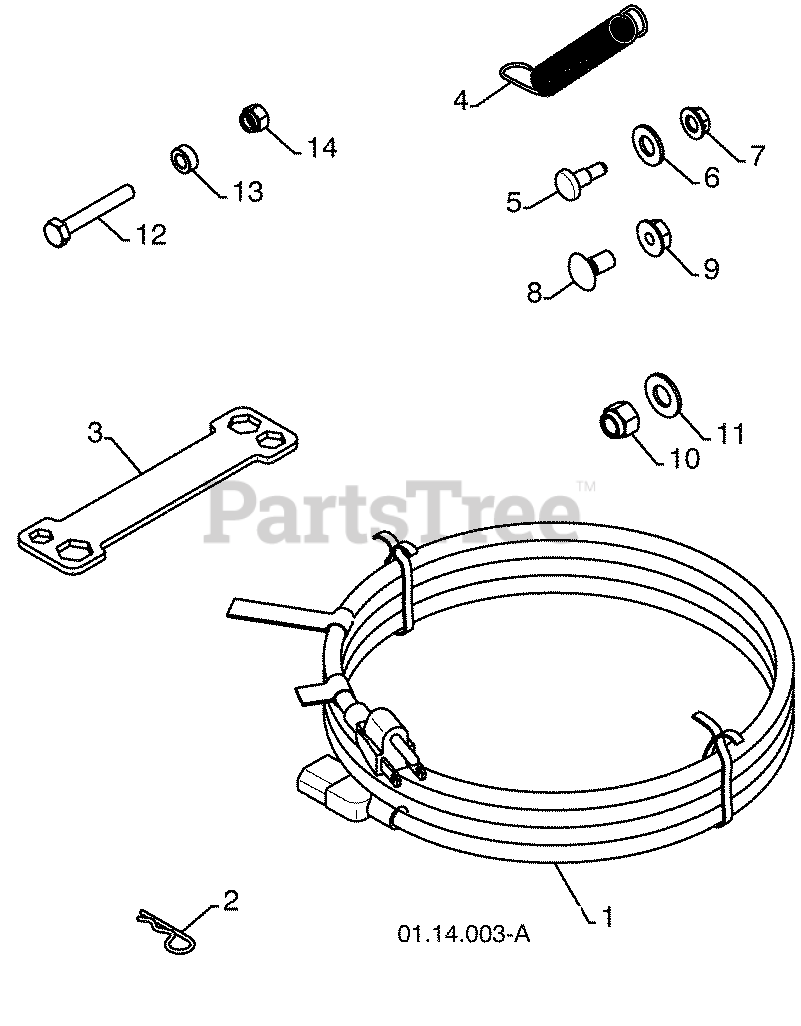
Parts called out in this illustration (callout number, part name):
1	POWER CORD
2	RETAINER PIN
3	WRENCH
4	REMOTE SPRING
5	SHOULDER BOLT 1/4-20
6	NYLON WASHER 1/4-20
7	LOCKNUT 1/4-20
8	CARRIAGE BOLT 5/16-18 X 5/8
9	LOCKNUT 5/16-18
10	LOCKNUT 3/8-16
11	WASHER 3/8
12	SHEAR BOLT 1/4-20 X 1-3/4
14	LOCKNUT 1/4-20
